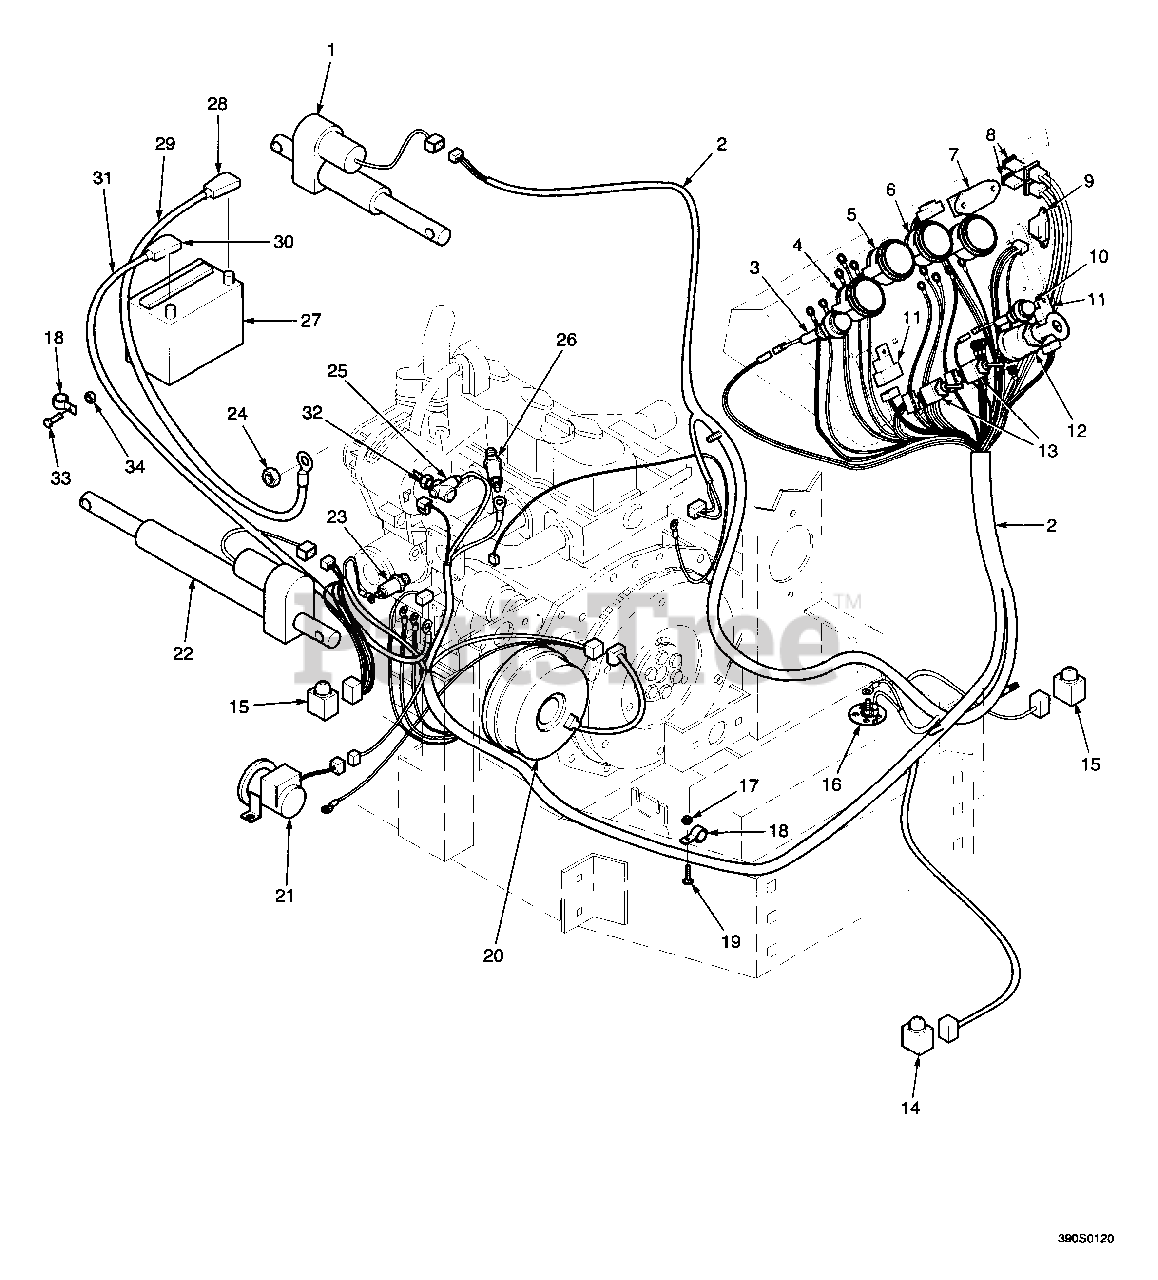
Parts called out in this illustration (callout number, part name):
1	Actuator, Cutting Height
2	Wire Harness
3	Indicator Light, Oil Pressure
4	Hourmeter
5	Gauge, Water Temperature
6	Gauge, Fuel Level
7	Timer, Delay Circuit
8	Fuse, 30 Amp
9	Timer, Glow Plug
10	Indicator Light, Glow Plug
11	Relay, Synchronize Start and Clutch Kill Circuit
12	Switch, Ignition
13	Switch, Deck Lift and Cutting Height
14	Switch, Safety - Parking Brake
15	Switch, Foot Pedal and Cutter Brake Interlocks
16	Sender, Fuel
17	Hex Locknut, Elastic Stop, 5/16-18
19	Carriage Bolt, 5/16-18 x 3/4
20	Electric Clutch
21	Fuel Pump, Electric
22	Actuator, Deck Lift
23	Sender, Oil Pressure
24	Hex Nut, M8-1.25
25	Cap, Alternator Terminal
26	Sender, Water Temperature
27	Battery
28	Cap, Battery Terminal - Black
29	Battery Cable, Black
30	Cap, Battery Terminal - Red
31	Battery Cable, Red
32	Hex Nut, M6-1.00
33	Serr. Fl. Hex Head Capscrew, 5/16-18 x 3/4
34	Serr. Fl. Hex Nut, 5/16-18
